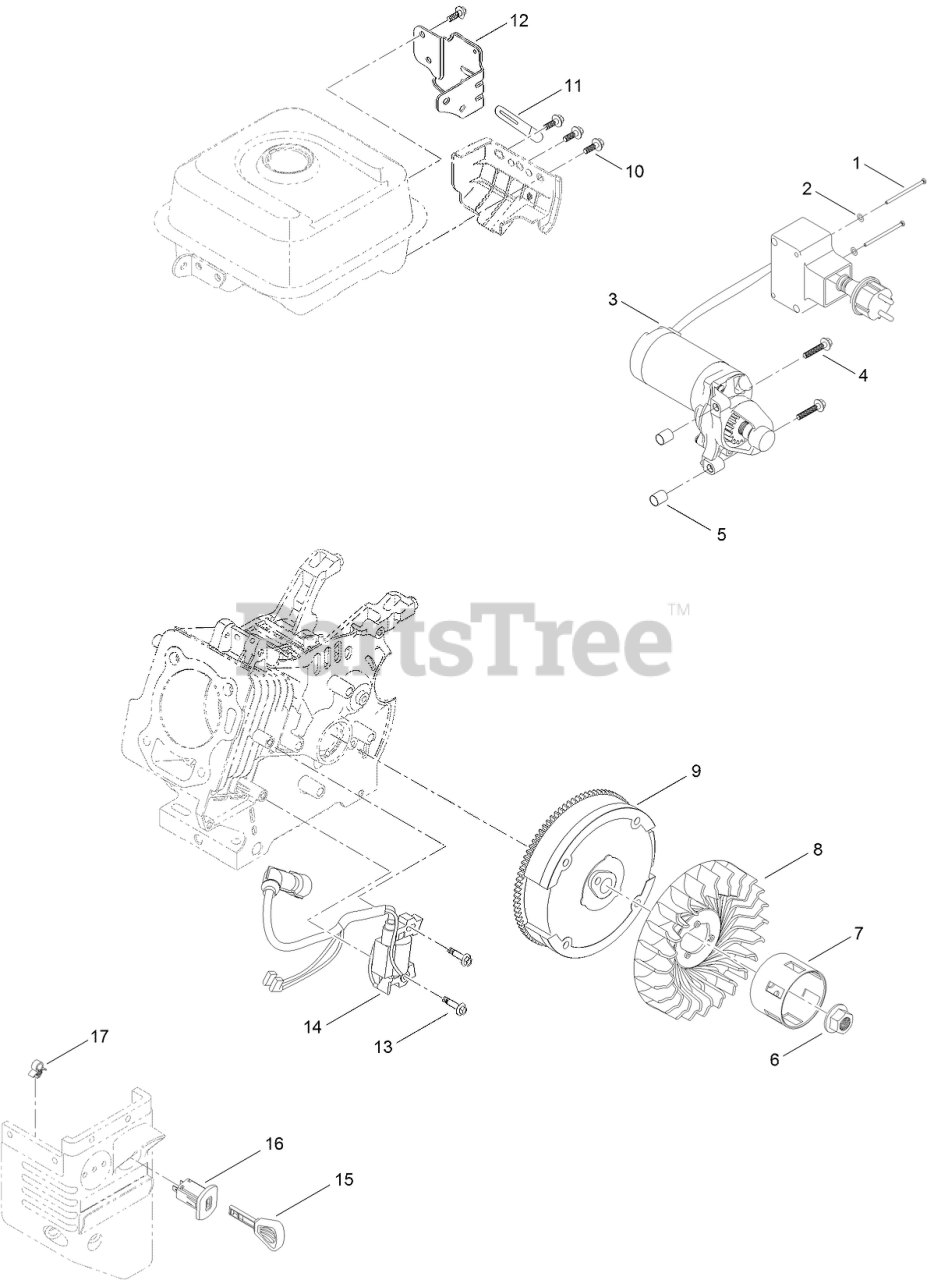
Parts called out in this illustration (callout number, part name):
1	SCREW-BHP
2	WASHER-PLAIN
3	MOTOR-STARTER
4	SCREW-FLANGE
5	PIN-DOWEL
6	NUT-FLANGE
7	CUP-STARTER
8	FAN-COOLING
9	FLYWHEEL AND RING GEAR ASM
10	SCREW-HHF
11	CLIP-HARNESS, WIRE
12	BRACKET-SWITCHBOX, STARTER
13	SCREW-HHF
14	IGNITION COIL ASM
16	SWITCH-KEY
